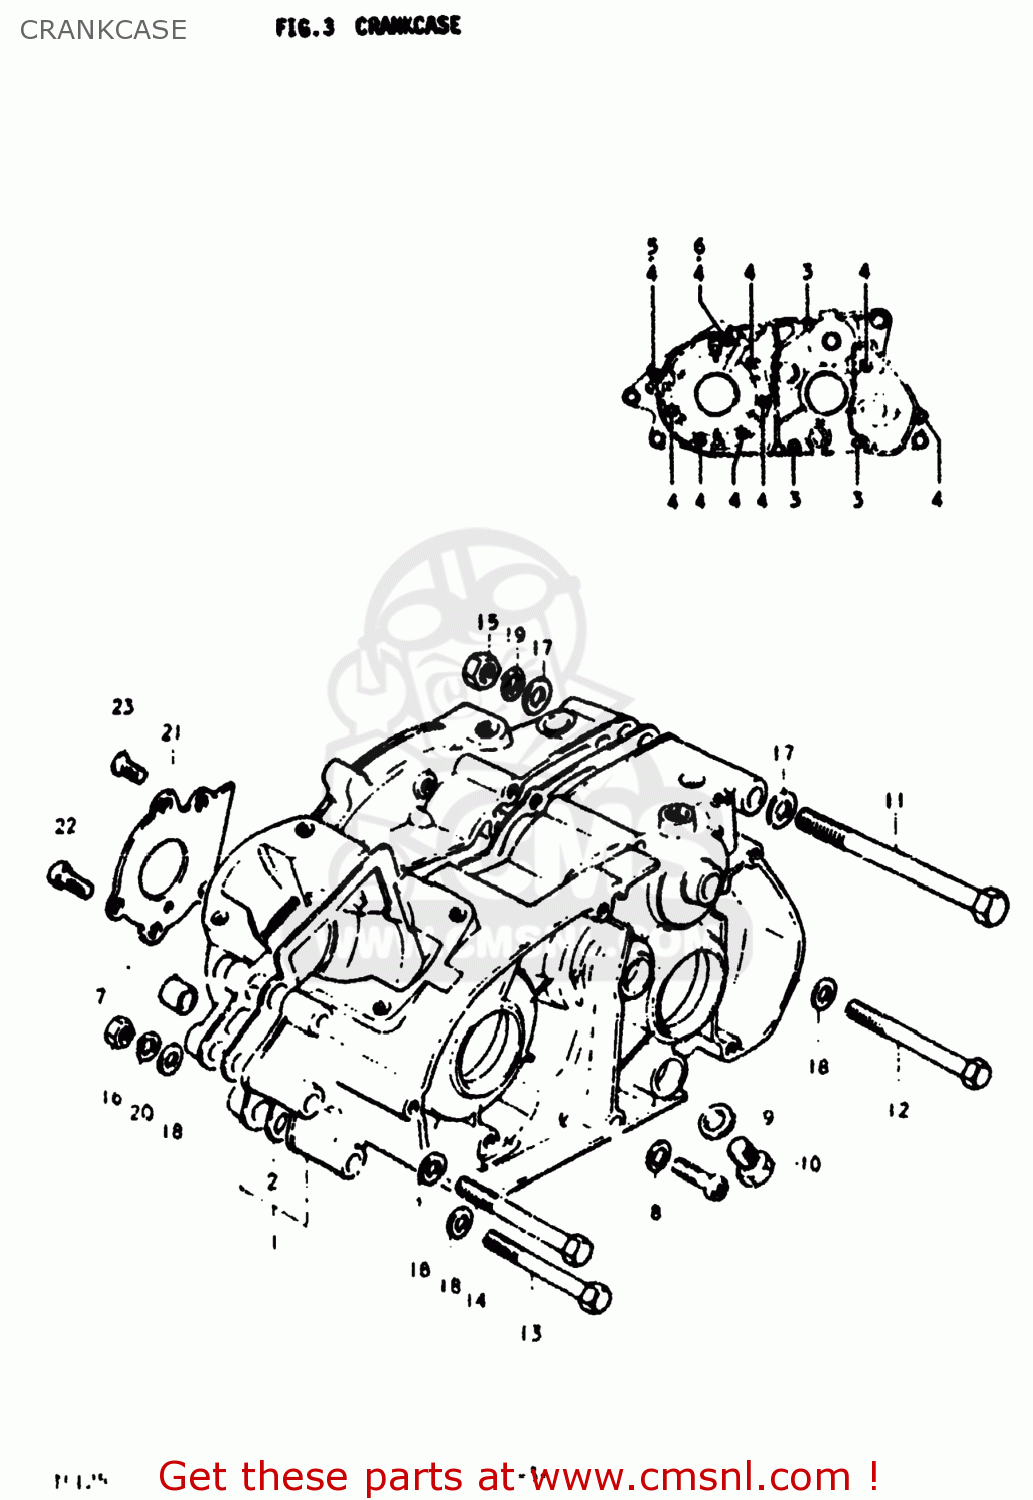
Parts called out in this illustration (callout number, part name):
1	CRANKCASE SET
2	GASKET,CRANKCASE (MCA)
3	SCREW
4	SCREW (6X45)
5	SCREW 6X80
6	SCREW 6X60
7	PIN
8	WASHER 6MM
9	GASKET(14X19.2X2) (NAS)
10	PLUG
11	BOLT 10X120
12	HEXAGON BOLT 8X80
13	BOLT,8X75
14	BOLT
15	NUT
16	NUT
17	WASHER
18	WASHER
19	LOCK WASHER
20	LOCK WASHER
21	PLATE,OIL RESERVOIR
22	SCREW
23	SCREW
